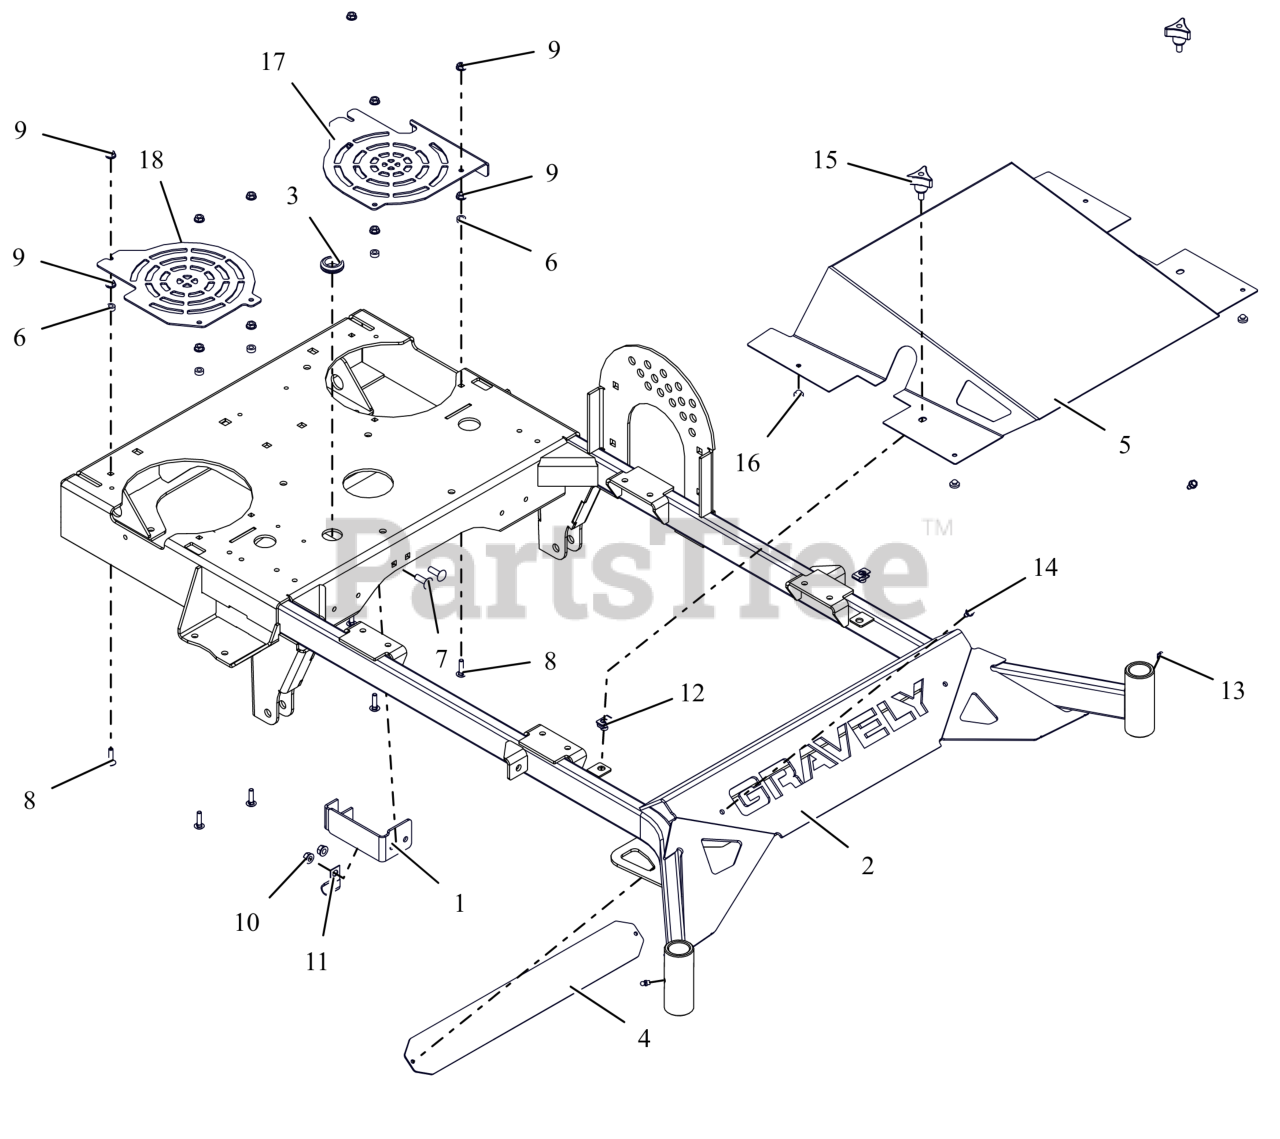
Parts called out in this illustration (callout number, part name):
1	WLDMT, CLUTCH STOP
2	WLDMT, FRAME 60" PRO WALK (RED)
3	GROMMET:RUB:.88IDX1.38ODX.14GR
4	BUMPER LOGO BACKING PLATE -BLK
5	SHIELD, FRONT 52" PRO-WALK (RED)
6	BSHG-SLV .265X.500X.219
7	BLT,RHSSN .31-18X1.00 G5 ZCC
8	BLT, RHSN .25-20X1.00 G5 ZCC
9	NUT-LK-CTR-FLG .25-20 ZC120
10	NUT,LK-CTR-FLG .31-18 GF ZCC
12	NUT-CLIP RETAINER 5/16-18X.56
13	FTG-LUBE .25-28X.256 SST
14	SCR-TAP .25-20X.50 HWH ZCC
15	KNOB,WING STUD 5/16-18 X .75
16	BUMPER GROMMET
17	GUARD, LH FAN (RED)
18	BRKT, BATTERY TRAY (RED)
